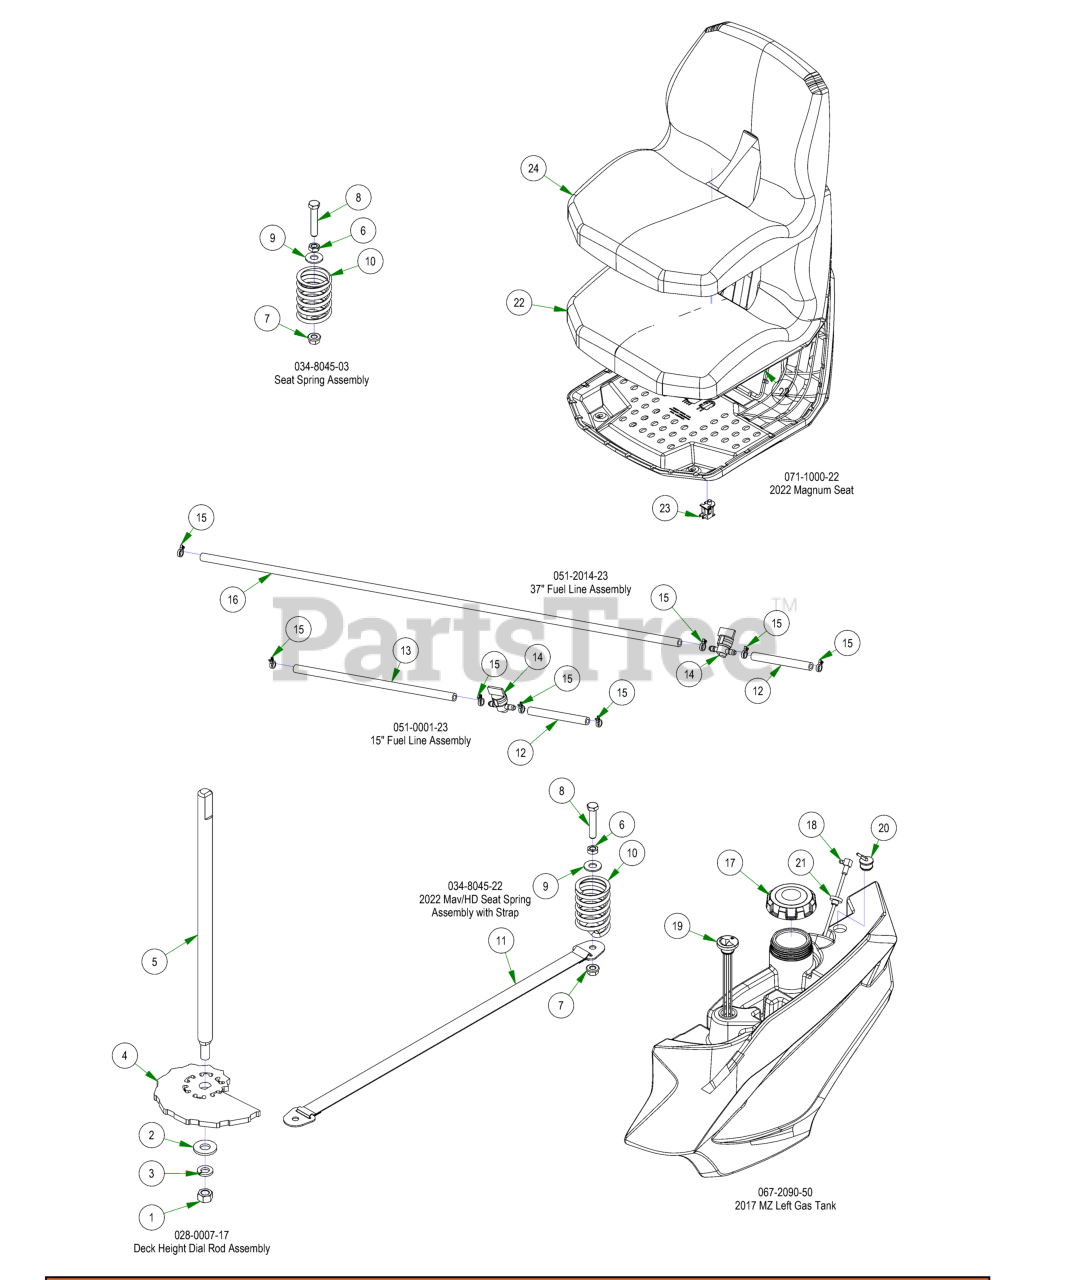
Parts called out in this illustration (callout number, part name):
1	3/8" Fine Threaded Jam Nut
2	3/8" Flat Washer
3	3/8" Lock Washer
4	2017 MZ/ZT Cam Plate
5	2017 Deck Height Dial Rod MZ
6	3/8-16 Half Jam Nut
7	3/8-16 HEX SERRATED FLANGE NUT HARD/ZINC
8	3/8-16 X 2 HEX CAP SCREW (GR.5) ZINC
9	3/8 FLAT WASHER USS (1" OD) ZINC
10	Seat Spring
11	Seat Strap with Buckles
12	4" 1/4 Fuel Line
13	11" 1/4 Fuel Line
14	2 Way Fuel Shut-Off Valve
15	1/4 Fuel Hose Clamp
16	37" 1/4 Fuel Line
19	Fuel Gauge w/Grommet
20	Rollover Valve W/Grommet
21	Pick-Up Grommet
22	SK120 Seat Foam for 071-1000-22
23	SeatSwitch for 071-1000-00/071-1000-22/071-2100-22
24	Bad Boy SK120 Cover with Logo for 071-1000-22
